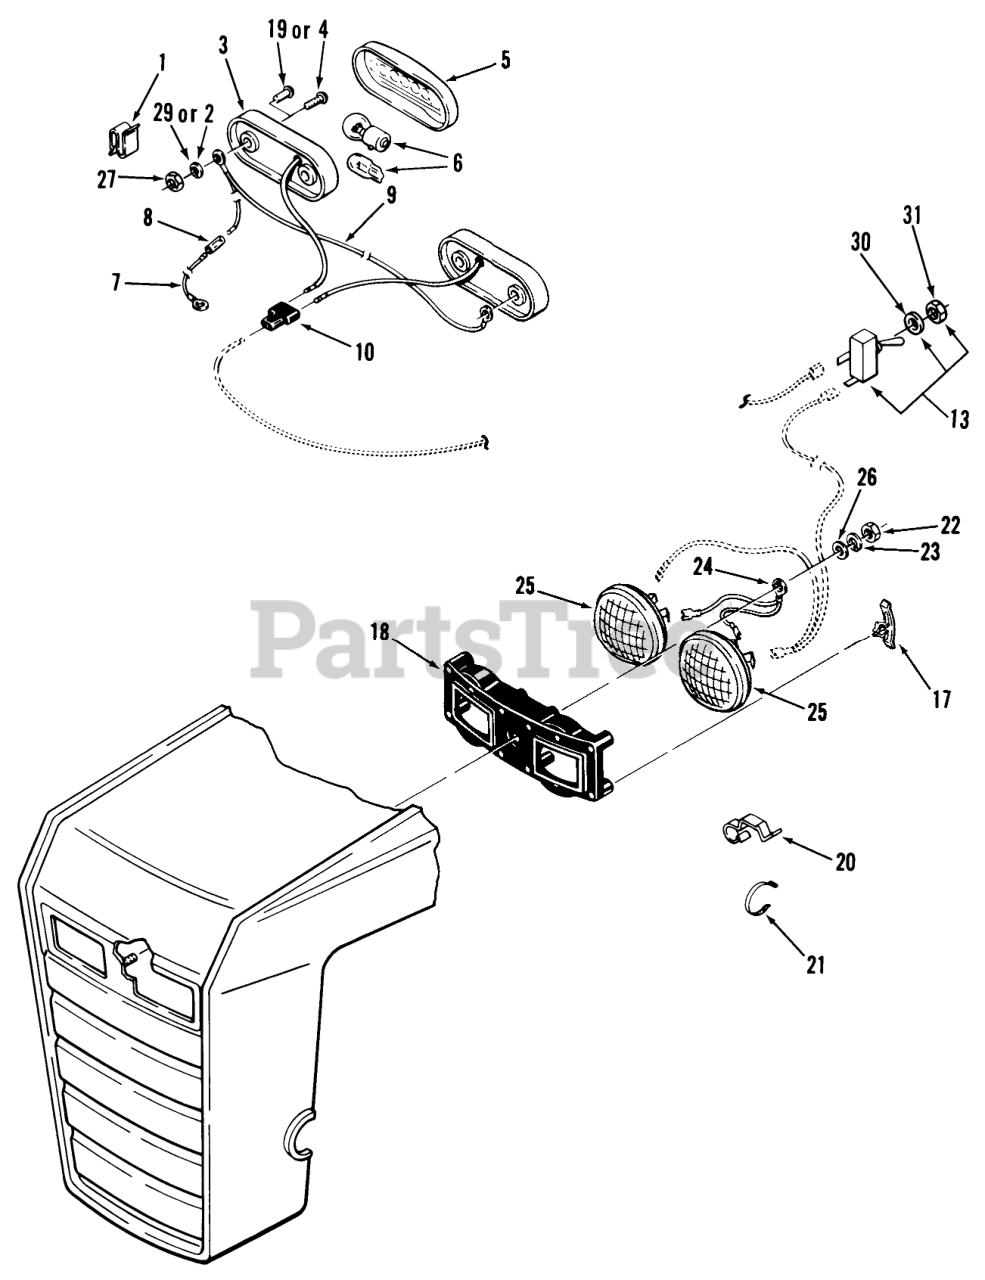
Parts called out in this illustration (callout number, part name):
1	SPEED CLIP
2	Lockwasher
3	BASE-TAIL LIGHT
4	Screw
5	Lens-Taillight
6	Bulb
6	LIGHT BULB
7	ASSEMBLY-WIRE
8	CONNECTOR 2 WIRE
9	Taillight Wire
10	CONNECTOR 3 WIRE
13	SWITCH-LIGHTS
17	CLIP-SPRING
18	Headlight Retainer
19	Poprivet
20	CLIP-WIRE
21	PLASTIC TIE
22	Nut
23	Washer-Lock
24	LIGHT GROUND WIRE
25	HEADLAMP
26	WASHER 5/16 SAE
27	Nut
29	WASHER
30	TAB-WASHER
31	NUT-HEX
